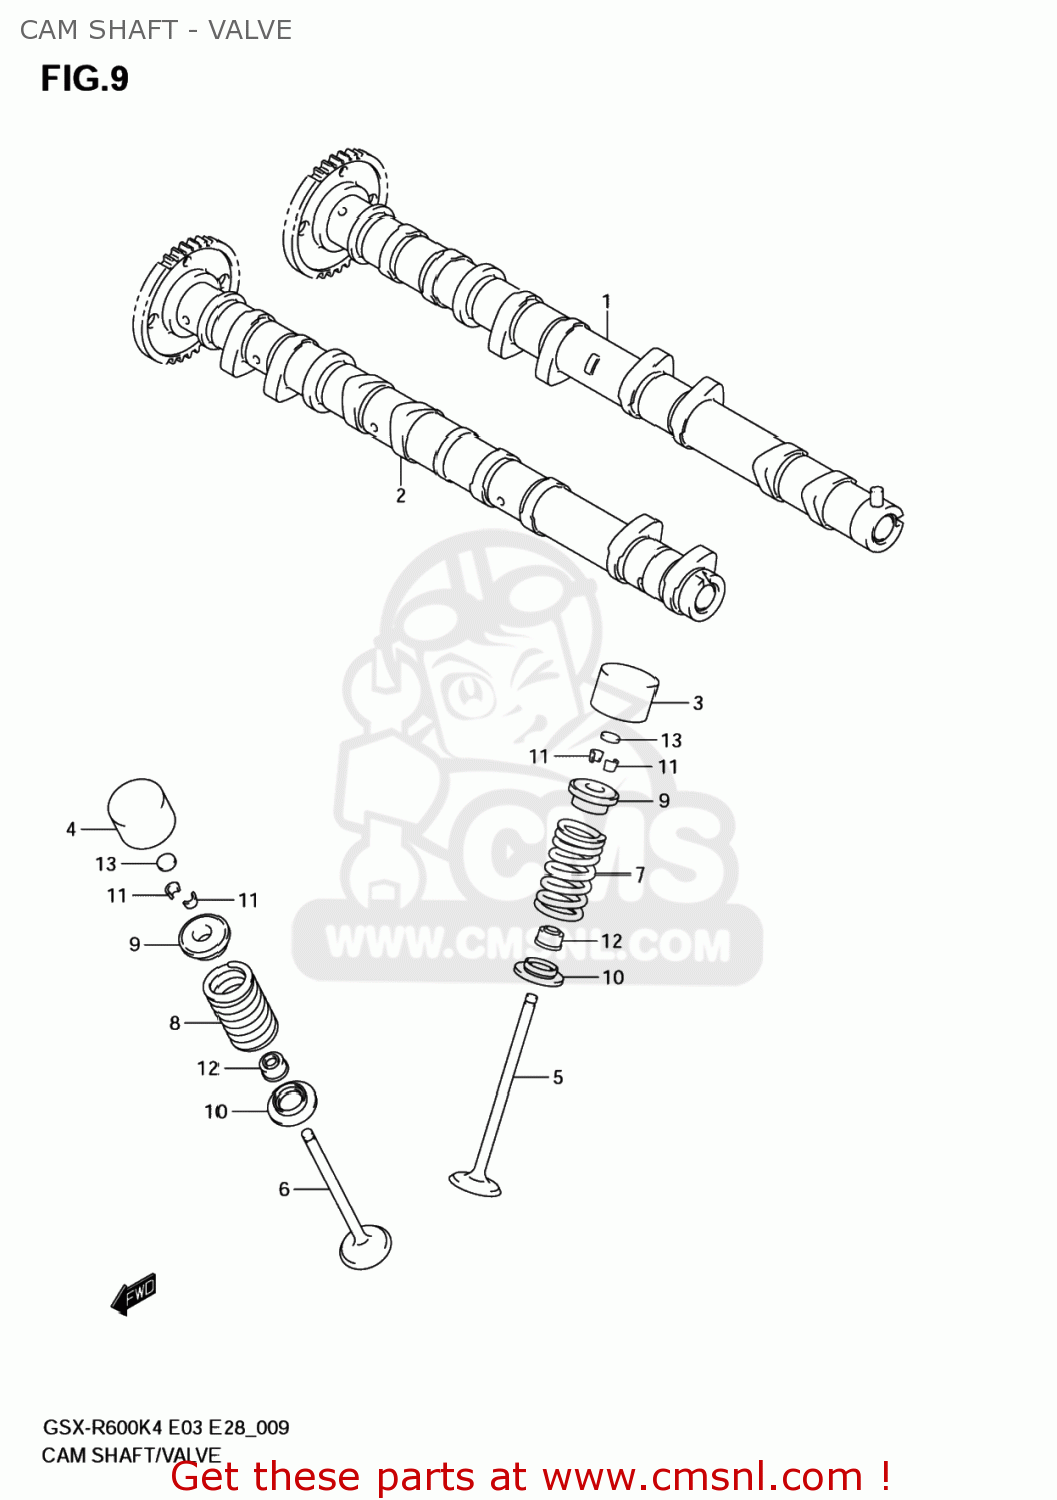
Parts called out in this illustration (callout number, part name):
1	CAMSHAFT,INTAKE
2	CAMSHAFT,EXHAUST
3	TAPPET,INTAKE
4	TAPPET,EXHAUST
5	VALVE,INTAKE
6	VALVE,EXHAUST
7	SPRING,VALVE INTAKE
8	SPRING,VALVE EXHAUST
9	RETAINER,VALVE SPRING
10	SEAT,VALVE SPRING
11	COTTER VALVE
12	SEAL,OIL(4.5X10X8)
13	SHIM,TAPPET
14	SHIM SET,TAPPET
15	CASE,TAPPET SHIM
